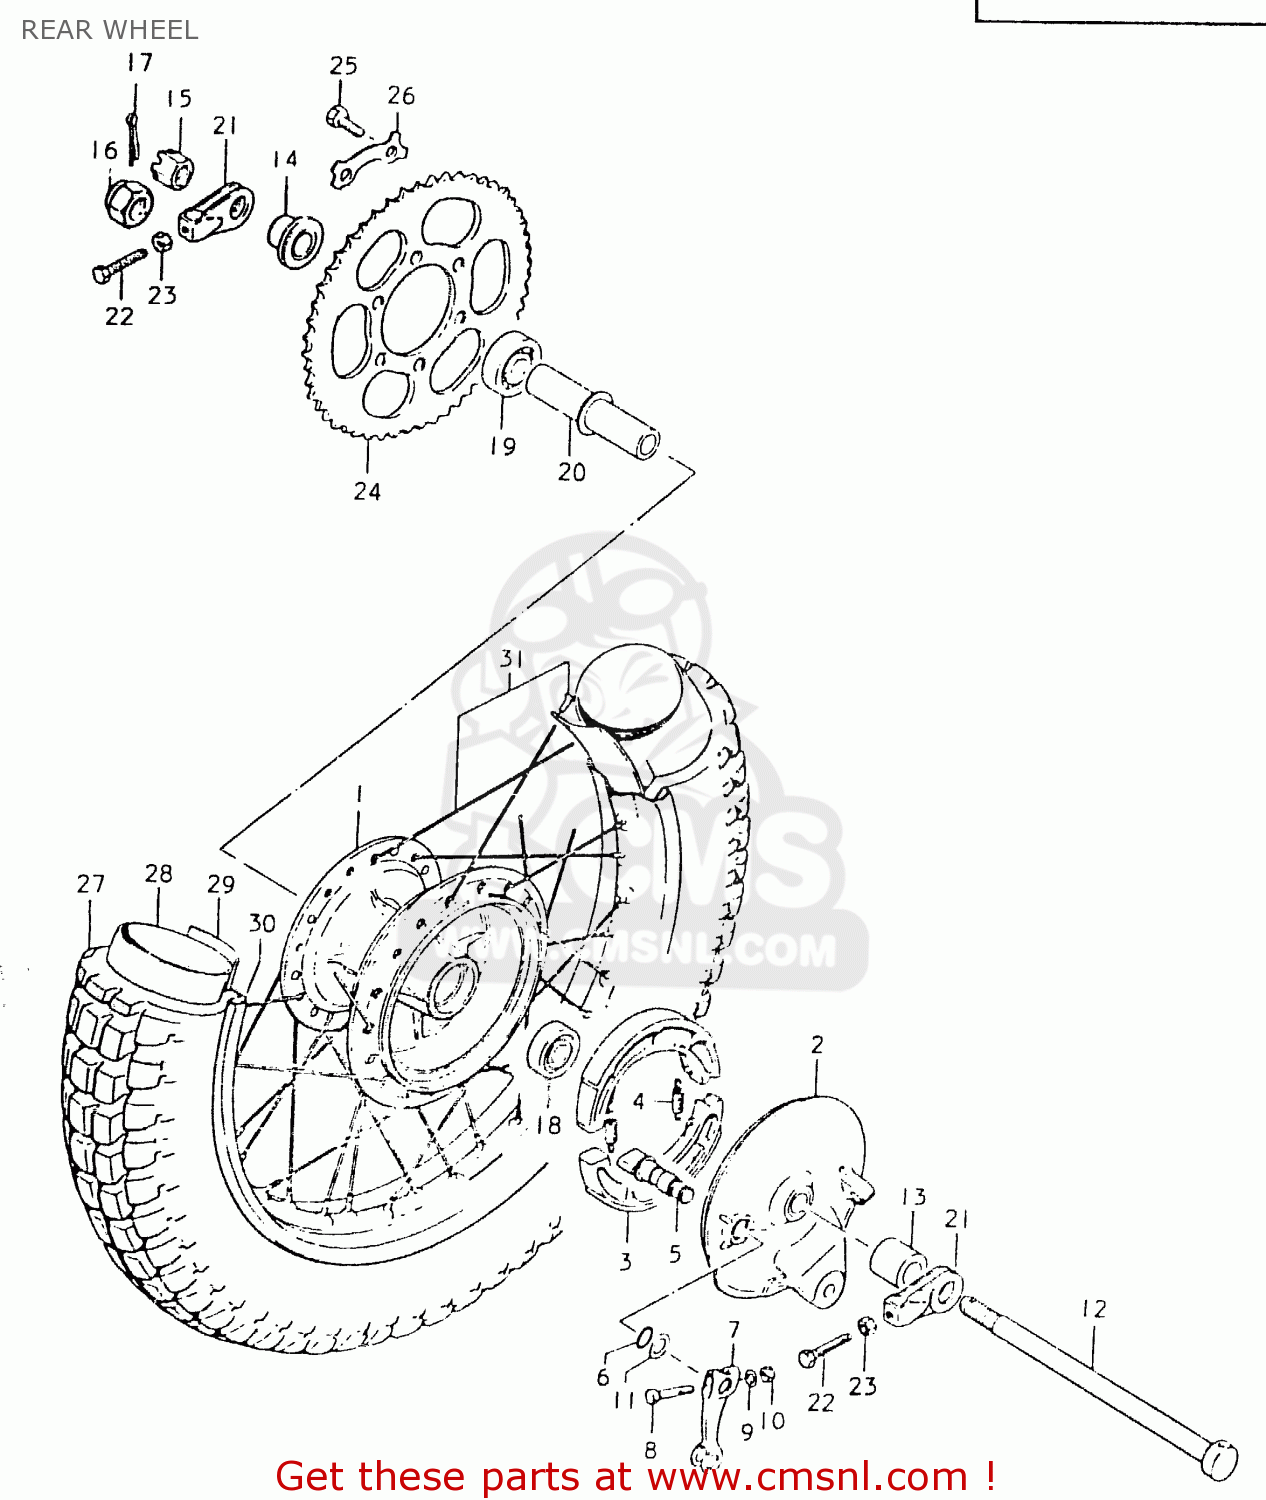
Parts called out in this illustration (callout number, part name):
1	HUB,REAR WHEEL
2	PANEL,RR BRAKE ANCHOR
3	SHOE,BRAKE
4	SPRING(L:34)
5	CAM,FRONT BRAKE
6	O-RING (D:2.4 ID:13.8)
7	LEVER,RR BRAKE CAM
8	BOLT 6X40
9	WASHER
10	NUT
11	WASHER (14.5X22X1.6)
12	AXLE,REAR
13	SPACER(15.2X22X26)
14	SPACER,RR AXLE,L
15	NUT
16	NUT
17	COTTER PIN
18	BEARING
19	BEARING
20	SPACER,RR WHEEL HUB BEARING
21	ADJUSTER,CHAIN
22	BOLT(8X40)
23	NUT
24	SPROCKET,REAR
25	BOLT(8X30)
26	WASHER
27	TIRE 4.10-18 105-458MM
28	TUBE ASSEMBLY,WHEEL,INNER
29	PROTECTOR,INNER TUBE
30	RIM,WHEEL(1.85X18)
31	SPOKE SET
